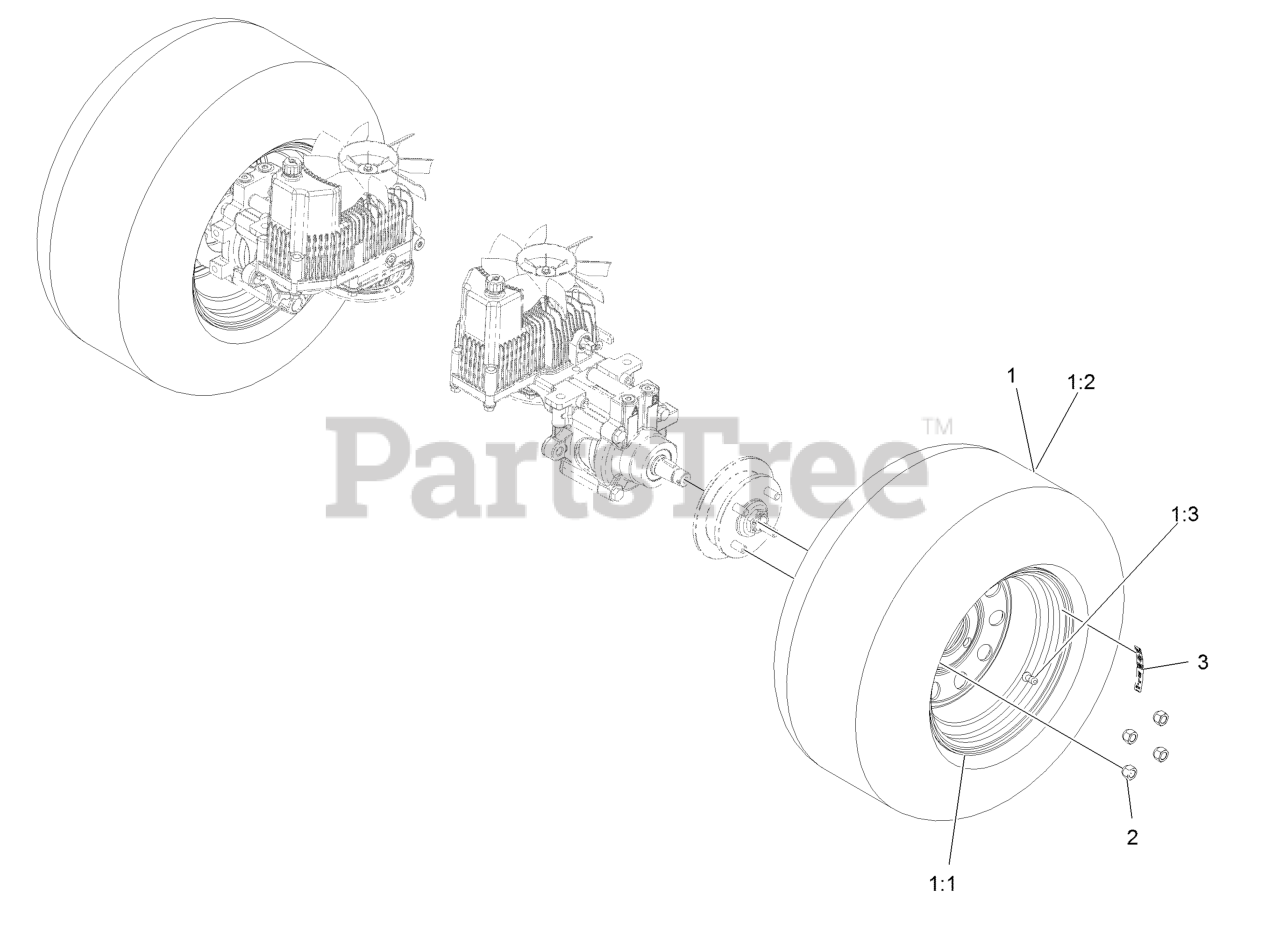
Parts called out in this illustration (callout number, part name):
1	Wheel And Tire ASM
1:3	Stem-Valve
2	Nut-Lug 1/2-20
3	Decal-Torque, Wheel Hub Lug
